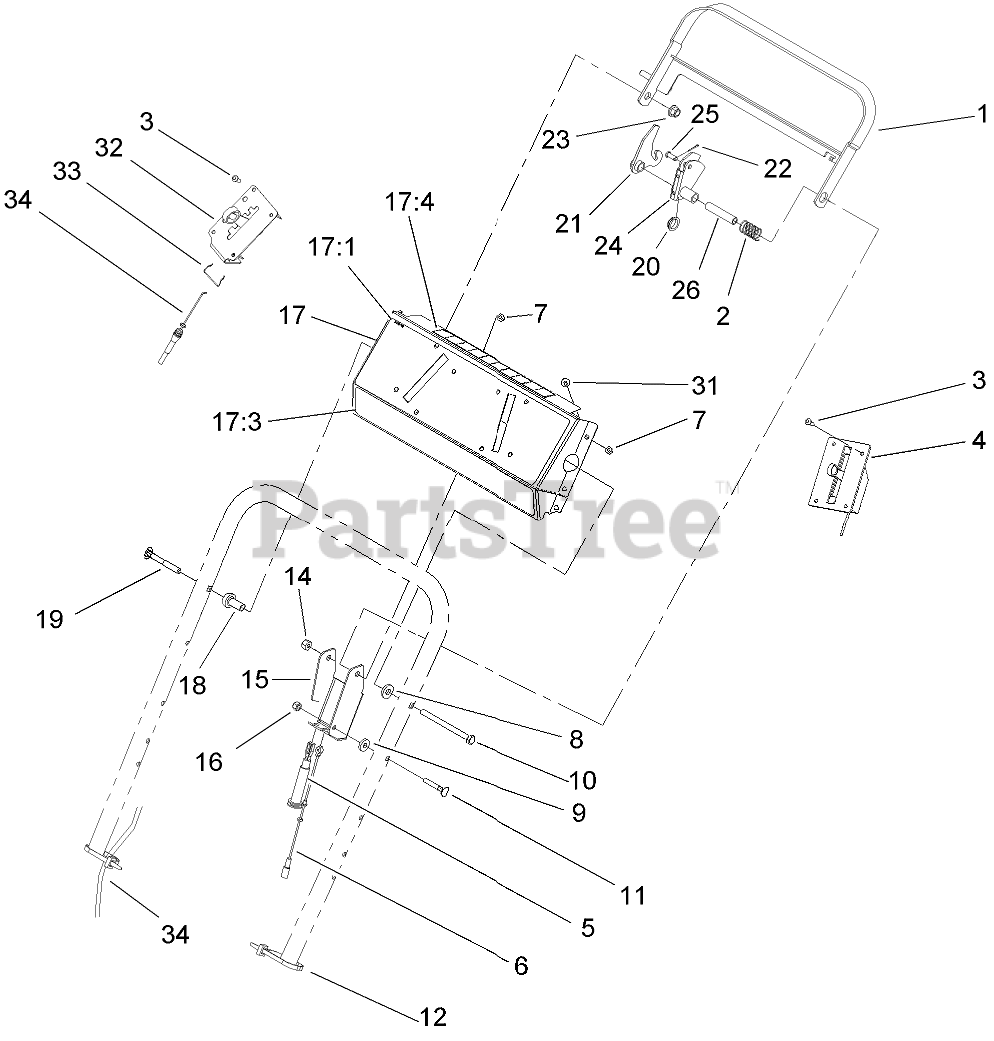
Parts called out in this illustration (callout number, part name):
1	BAR-CONTROL
2	SPRING-CONTROL
3	SCREW-PPH
4	CONTROL-THROTTLE
5	CABLE-TRACTION
6	CABLE-CLUTCH
7	NUT-LOCK, NI
8	SPACER
9	SPACER
10	SCREW-HH
11	SCREW-HANDLE
12	TIE-CABLE
14	NUT-LOCK, NI
15	BRACKET-CONTROL
16	NUT-LOCK, NI
17	PANEL ASM
17:1	DECAL-PANEL, CONTROL
17:3	Decal-Panel
17:4	DECAL-PANEL, REAR
18	SPACER-SUPPORT
19	SCREW
20	BUSHING-FLANGE
21	LEVER-TRACTION
22	PIN-COTTER
23	NUT-LOCK, NI
24	LEVER-BBC
25	PIN-CABLE
26	SPACER-BRACKET, CONTROL
31	SCREW-HWHTF
32	CONTROL-SHIFT
33	RETAINER-CABLE, THROTTLE
34	CABLE-SHIFT
